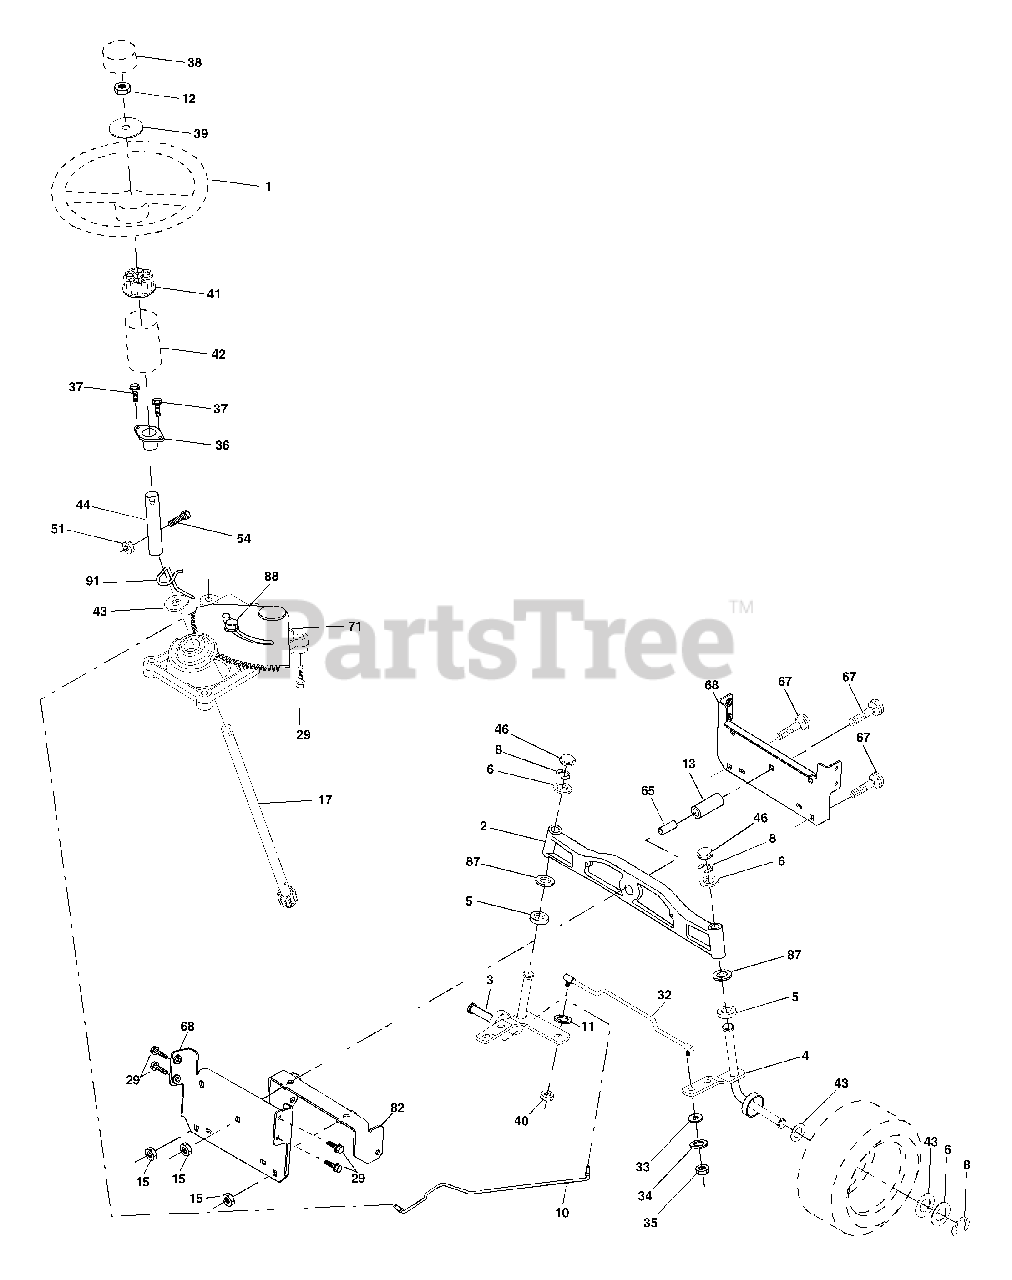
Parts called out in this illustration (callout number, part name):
1	Wheel Steering
2	Axle Asm Front
3	Spindle Asm Lh
4	Spindle Asm Rh
5	Bearing Race Thrust Harden
6	Washer 25/32 X 1 5/8 X 16ga
8	Ring Klip #t5304-75
10	Link Drag Extended
11	Lockwasher
12	Nut Hex Jam Toplock 1/2-20 Unf
13	Spacer Bearing Axle Front
15	Hex Flange Lock
17	Shaft Asm Strg
29	Screw 3/8-16x3/4
32	Rod Tie
33	Washer 11/32 x 3/4 x 16 Ga.
34	Washer lock 5/16
35	Nut Crownlock 5/16-24
36	Bushing Strg 5/8 Id Dash
37	Screw TT #10-32 x 5 x 3/8 Flange
38	Insert Cap Strg
39	Washer 9/16 ID x 1-1/2 OD 11 Gr
40	Locknut Center
41	Adaptor Wheel Strg
42	Boot Dash Steering
43	Washer 25/32 X 1 1/4 X 16 Ga
44	Extension Steering
46	Cap Spindle Fr Top Blk
51	Nut Crownlock 1/4-28
54	Bolt Hex 1/4-28unf x 1-1/4 Gr. 8
65	Spacer Brace Axle
67	Bolt Rdhd Sq 3/8-16 Unc x 2-3/4
68	Brace Axle
71	Steering Asm
82	Bracket Susp Chassis Front
87	Washer Flat
88	Bolt Shoulder 7/16-20
91	Clip Steering
